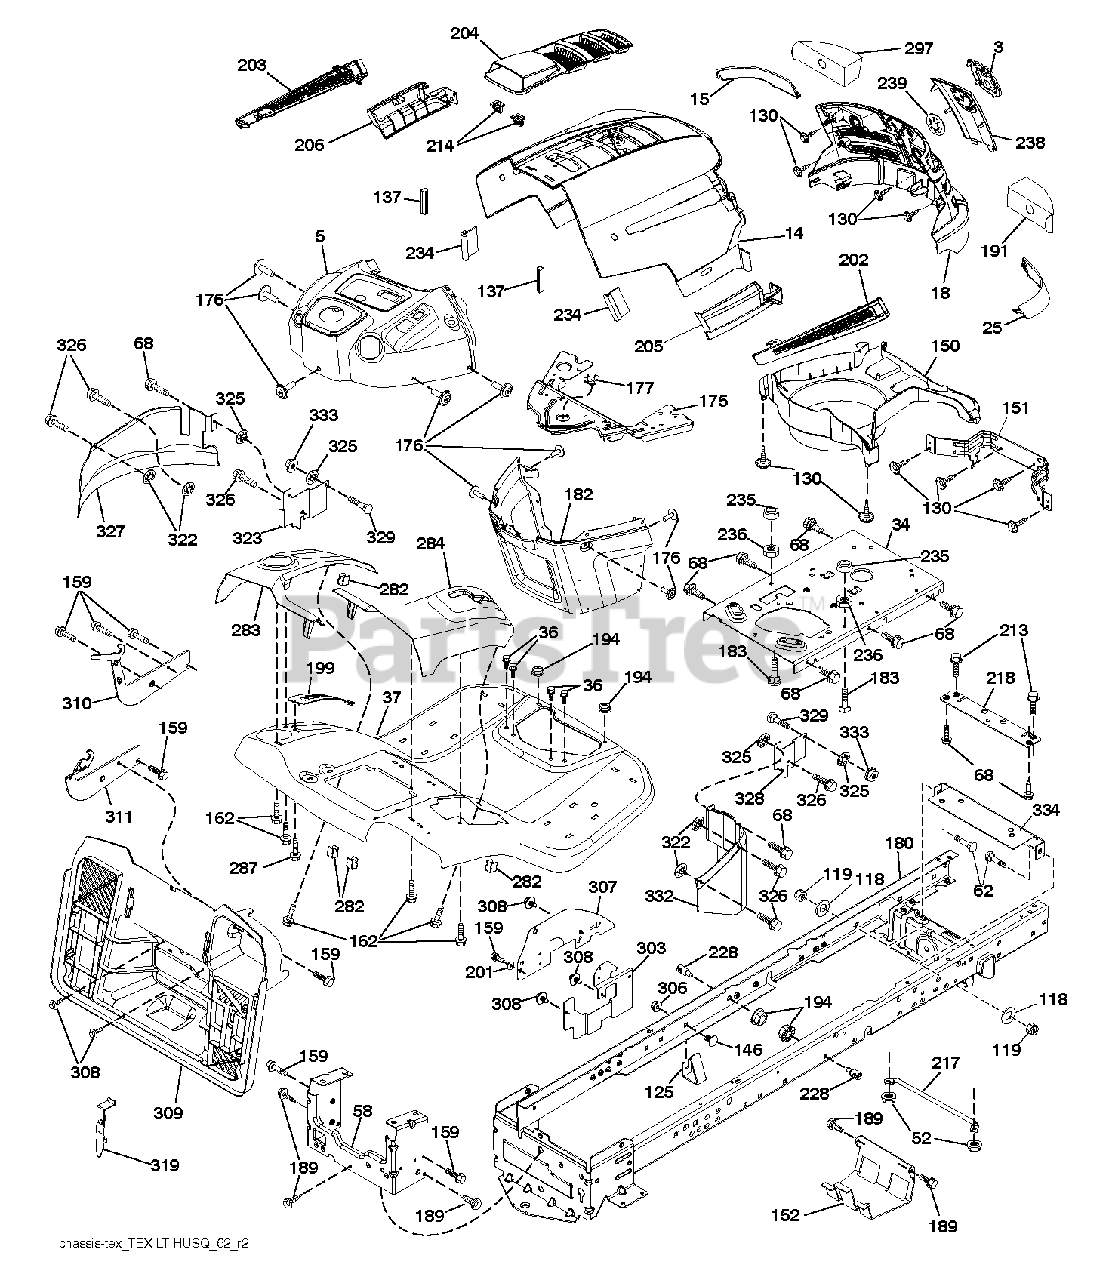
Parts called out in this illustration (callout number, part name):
3	LOGO.HUSQ.GT.LT.CROWN.H
5	DASH.UP.HU.LT.CBL.CLTCH.CHG.PT
14	HOOD.HUSQVARNA.LT.ORANGE
15	LENS.HUSQVARNA LT.RH
18	GRILLE.SVC.HUSQVARNA.GREY
25	LENS.HUSQVARNA LT.RH
34	PLATE.ENGINE.10GA.CRD.GENII
36	SCREW 5/16"
52	LOCKNUT
58	DRAWBAR UPPER 2PC SMALL FENDER
62	BOLT D
68	SCREW LT
118	WASHER
125	CLIP.FUEL.LINE
130	SCREW.#10 X 0.750.BOS
137	BUMPER DASH
146	BOLT.RDHD.SHT.SQNK.3/8-16X5/8
151	BRACKET PIVOT
152	SHIELD.BROWNING.W/TEX
159	SCREW, 3/8-16X3/4
162	SCREW.HI-LO.CONSOLE
175	CROSSMEMBER
176	SCREW.#10-24X5/8.RN.QU
177	BUSHING STEERING
180	CHASSIS.WLDMNT.14GA.2PC.18".TI
182	DASH.LOWER.PREDATOR LT
183	BOLT.5/16-18X1-1/4 FULL THD
189	SCREW
191	INSERT.REFLECTIVE.RH.
194	NUT LOCK HEX FLANGE 5/16-18
199	PLATE DECK LIFT
201	WASHER
202	VENT.SIDE.HUSQVARNA.LT.RT
203	VENT.SIDE.HUSQVARNA.LT.LFT
204	SUBASM.TOP.VENT.HUSQ.LT
205	SKIRT.SIDE.HUSQVARNA.LT.RT
206	SKIRT.SIDE.HUSQVARNA.LT.LEFT
213	BOLT
214	CLIP.RETAINER.TINNER.
217	ROD.PIVOT.HOOD
218	X-PIECE.HOOD.STOP.NON/
228	STUD.FASTNER.W/ANTI-ROTATE
234	BUMPER.HOOD.TEX.HUSQVARNA
235	SPACER FENDER
236	NUT.CENTERLOCK.5/16-
238	TRIM.HUSQ LT.668
282	CLIP.RETAINER.CONSOLE.LT.HUSQ
283	CONSL.DECKLIFT.LH.SRD.TEX.CRD
284	CONSL.SHFT.PEDAL.RH.SRD.TEXCRD
287	SCREW 1/4X20
297	INSERT REFLECTIVE
303	SHIELD CHASSIS LEFT
306	NUT LOCK FLG 3/8-16 UNC
307	SHIELD.UPPER.CRD.SRD.ISO
308	BOLT, 5/16-18 X 1 3/4
309	BACKPLATE.BAGGER.V2.SRD
310	BRACKET BRACKET.LH REAR BAG HA
311	BRACKET BRACKET.RH REAR BAG HA
319	BRACKET.ACTUATOR.BAGGER.SRD
322	PALNUT 1/4
323	GUARD FRONT LEFT
325	WASHER 5/16"
326	SCREW 14-20 X 5/8
327	GUARD LEFT
328	GUARD FRONT RIGHT
329	BOLT
332	GUARD RIGHT
333	NUT.71038.31-18.HEX.NYLOCK
334	BRACKET.ENGINE
